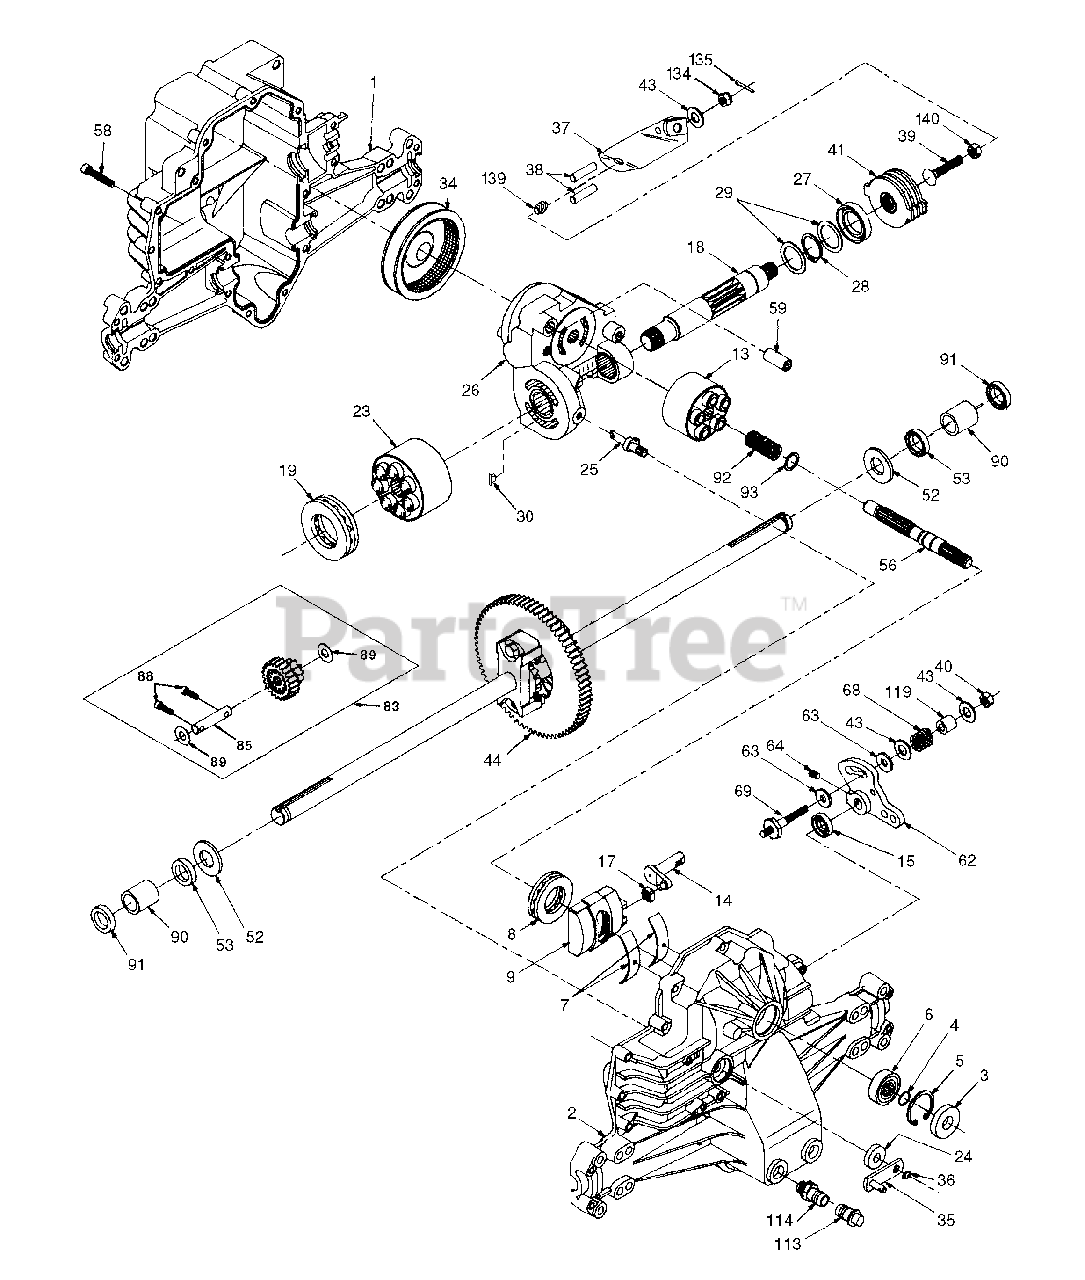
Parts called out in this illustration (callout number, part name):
1	Housing, Lower
2	Assembly, Upper Housing
4	Ring, Wire Retaining
5	Ring, Retaining
6	Bearing, Shaft Ball
7	Bearing, Cradle
8	Bearing, Thrust 30 x 52 x 13
9	Swashplate, Variable
13	Block, Cylinder Assembly
14	Arm, Trunnion
17	Guide, Slot
18	Shaft, Motor
19	Bearing, Thrust 42 x 68 x 16
23	Block, Cylinder Assembly
24	Seal, Lip 10 x 25 x 7
25	Actuator, Bypass
26	Center Section Assembly Kit
27	Seal, Lip 26 x 42 x 8
28	Ring, Retaining
29	Washer 26 x 35 x 1
30	Plate, Bypass
34	Oil Filter Element
35	Arm, Bypass
36	Ring, Retaining
37	Arm, Actuating
38	Pin, Actuating
39	Bolt 5/16-24 x 1-3/4
40	Locknut, Hex 5/16-24 UNJC
41	Brake Rotor/Stator Kit
43	Washer 7/16 x 7/8 x .060
44	Differential Assembly
52	Washer 3/4 x 1.5 x .13
53	Seal .75 x 1.25 x .250
56	Shaft, Input
58	Bolt 1/4-20 x 1.38
59	Pin .5 OD x .43 ID x .750
62	Arm, Control
63	Puck, Dampener
69	Stud 5/16-24
83	Jackshaft Assembly
88	Screw, Cap
89	Washer 7/16 x 1 x 1/2
90	Sleeve Bearing
91	Seal, Wiper
92	Spring, Block
93	Washer, Block Thrust
113	Cap, Vent Assembly
114	Fitting, O-Ring Assembly
119	Spacer
134	Nut, Castle 5/16-24
135	Pin, Cotter
139	Spring, Compression
140	Nut, Hex 5/16-24
